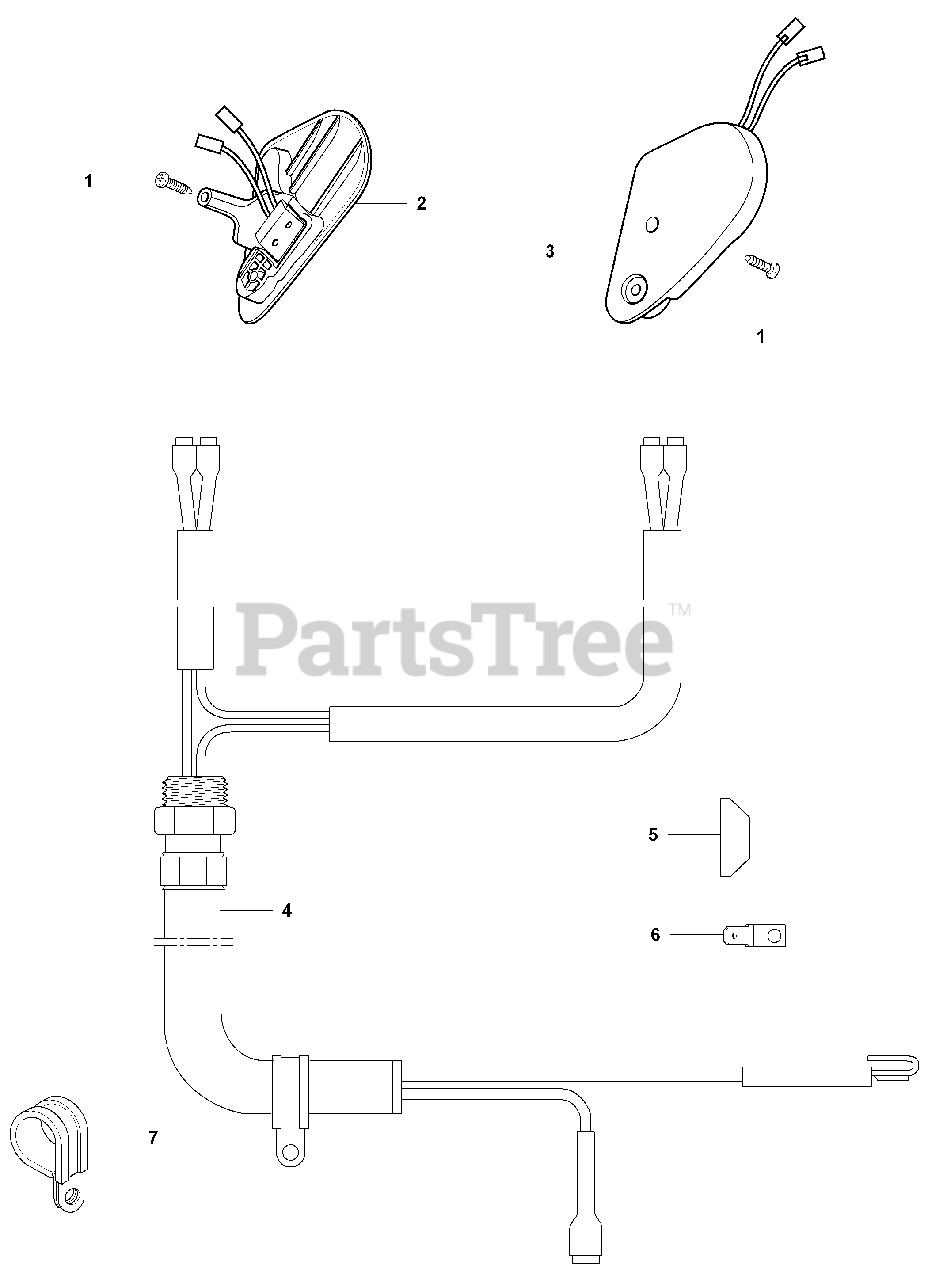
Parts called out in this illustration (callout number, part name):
2	STOP SWITCH
3	STOP SWITCH
5	SPACING BLOCK
6	CONNECTION PLATE
